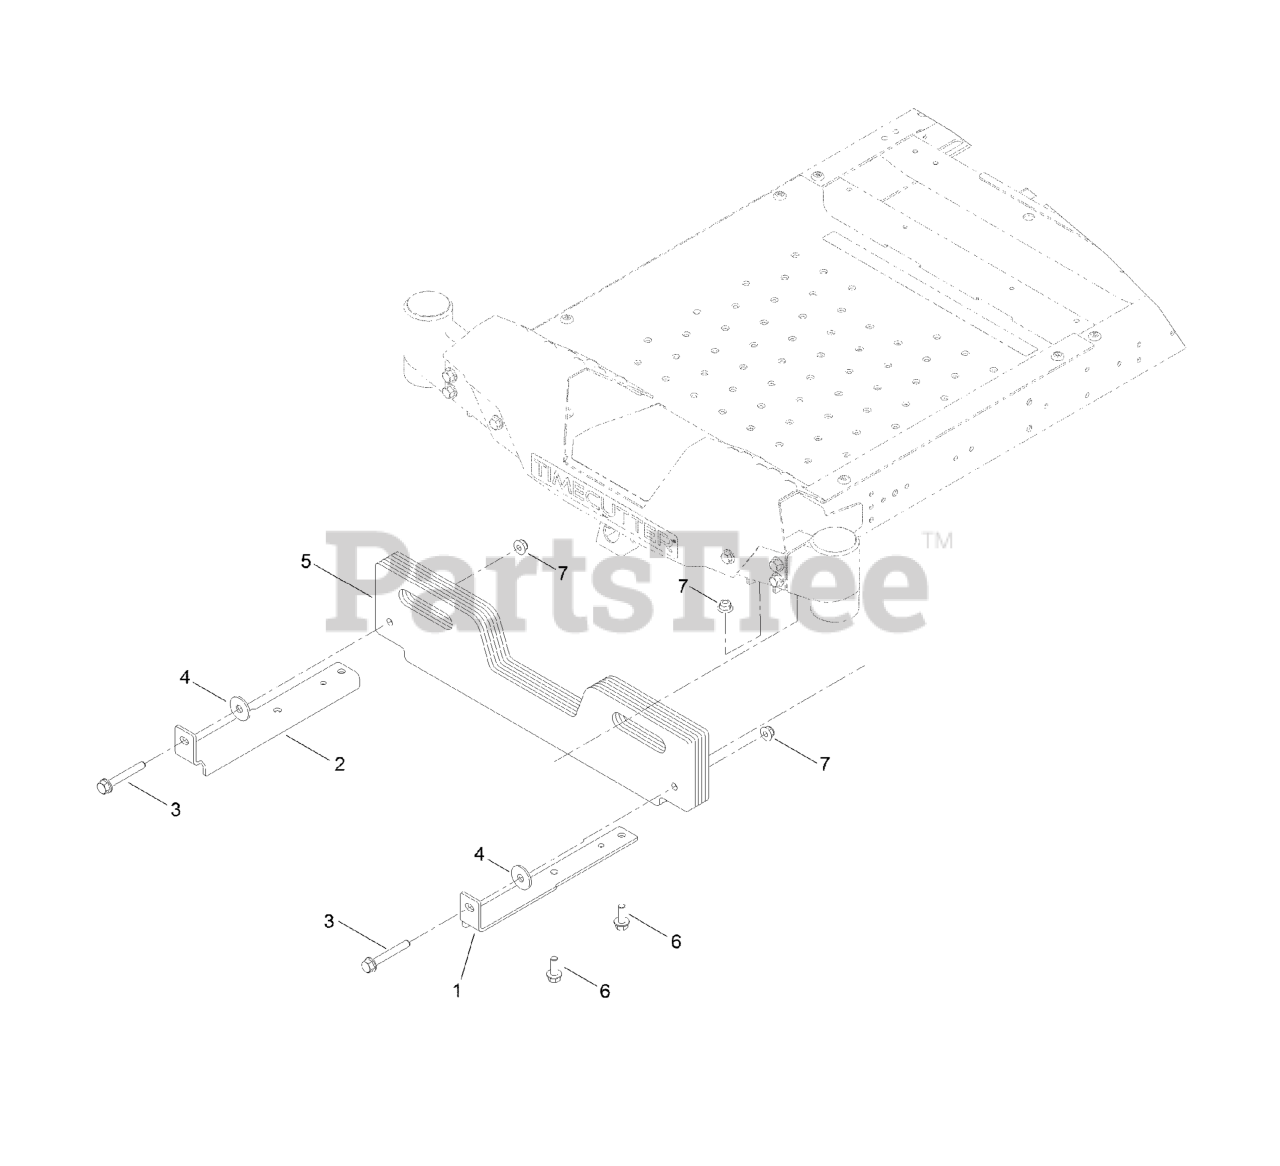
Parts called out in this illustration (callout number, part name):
1	Bracket-Weight, LH
2	Bracket-Weight, RH
3	Screw-Spcl
5	Weight-Bagger
6	SCREW-HHF
7	Nut-HF, NI
